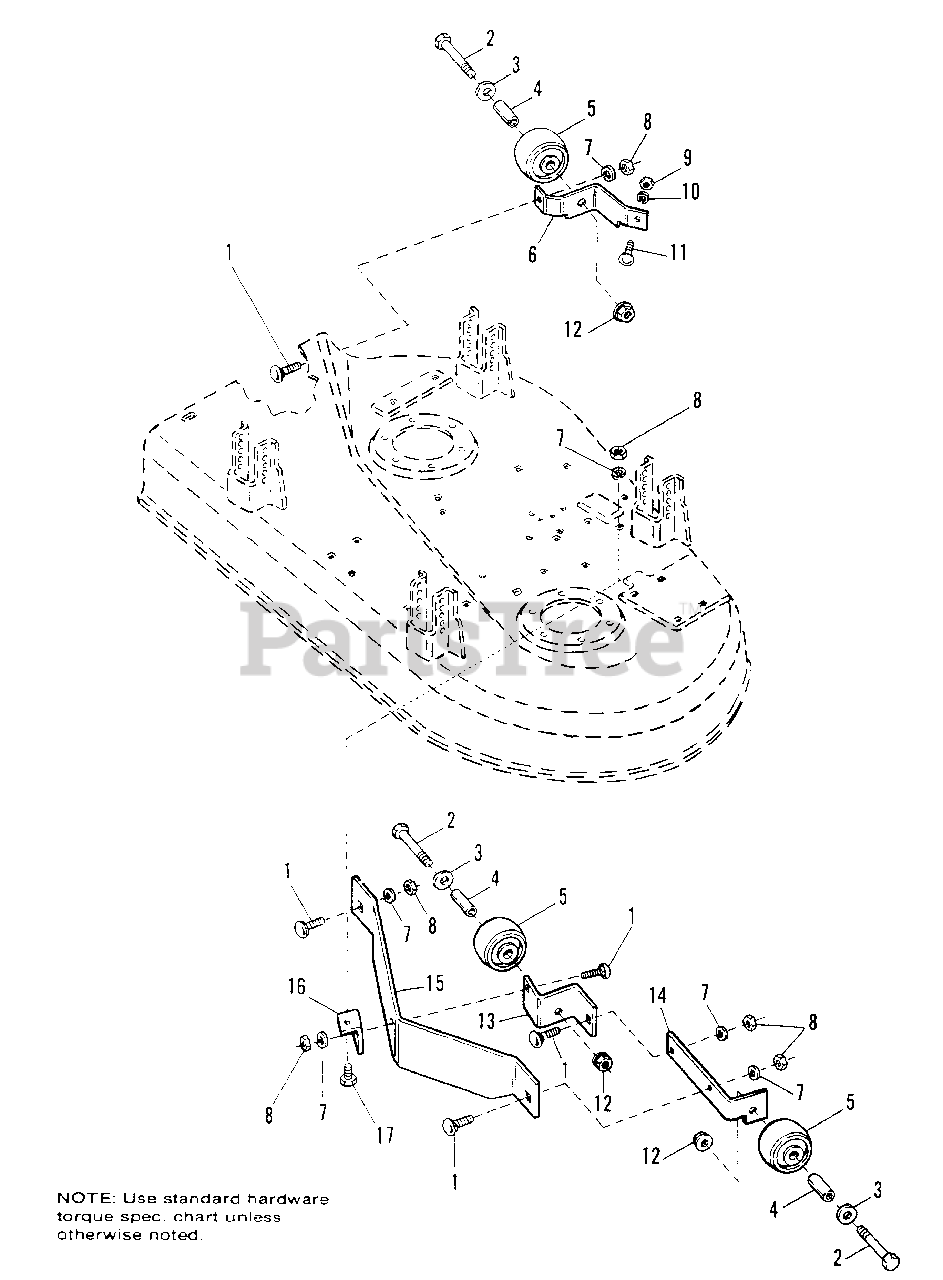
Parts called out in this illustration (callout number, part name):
1	BOLT, Carriage, 5/16-18 x 7/8
2	CAPSCREW, Hex, 1/2-13 x 3
3	WASHER, 9/16 x 1-1/4
5	GAUGE, Roller
6	BRACKET, Roller, Right
7	LOCKWASHER, 5/16
8	NUT, Hex, 5/16-18
9	NUT, Hex, 1/4-20
10	LOCKWASHER, 1/4
11	BOLT, Carriage, 1/4-20 x 3/4
12	NUT, Flange, Centerlock, 1/2-13
13	BRACKET, Roller, Center
14	BRACKET, Roller, Left
15	BAFFLE
16	BRACKET, Mower to Baffle
17	CAPSCREW, Hex Hd ., 5/16-18 x 3/4
